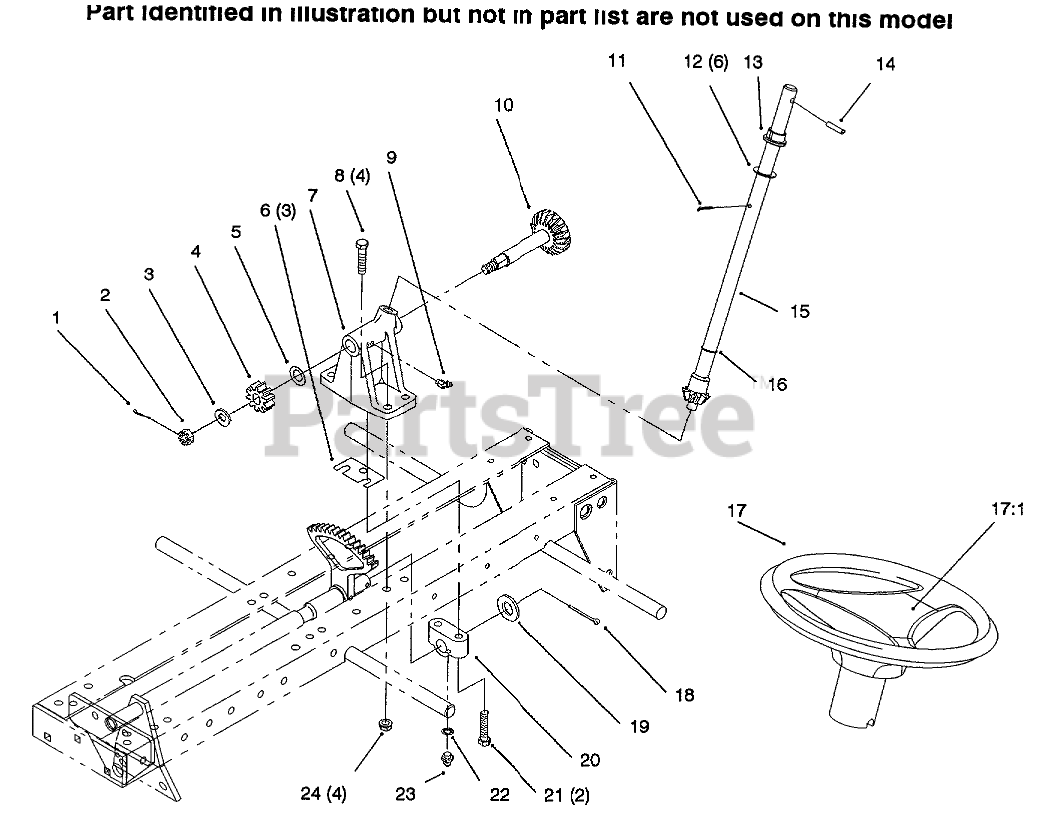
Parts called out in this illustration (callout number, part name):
1	PIN-COTTER
2	NUT-SHH
3	WASHER-FLAT
4	PINION-SPUR
5	WASHER
6	SHIM-.010
7	Steering Support
8	SCREW-HH
9	FITTING-GREASE
10	WLDMT-C SHAFT
11	PIN-COTTER
12	WASHER-SHIM
13	BEARING-FLANGED
14	PIN-ROLL
15	WLDMT-STRG SHAFT
16	O-RING
17	WHEEL - STEERING 15"
17:1	COVER-WHEEL
18	PIN-COTTER
19	WSHR-.765X1.125X.060
20	BLOCK-BEARING
21	Bolt
22	WASHER-LOCK
23	ZERK FITTING
24	NUT-LOCK, NI
